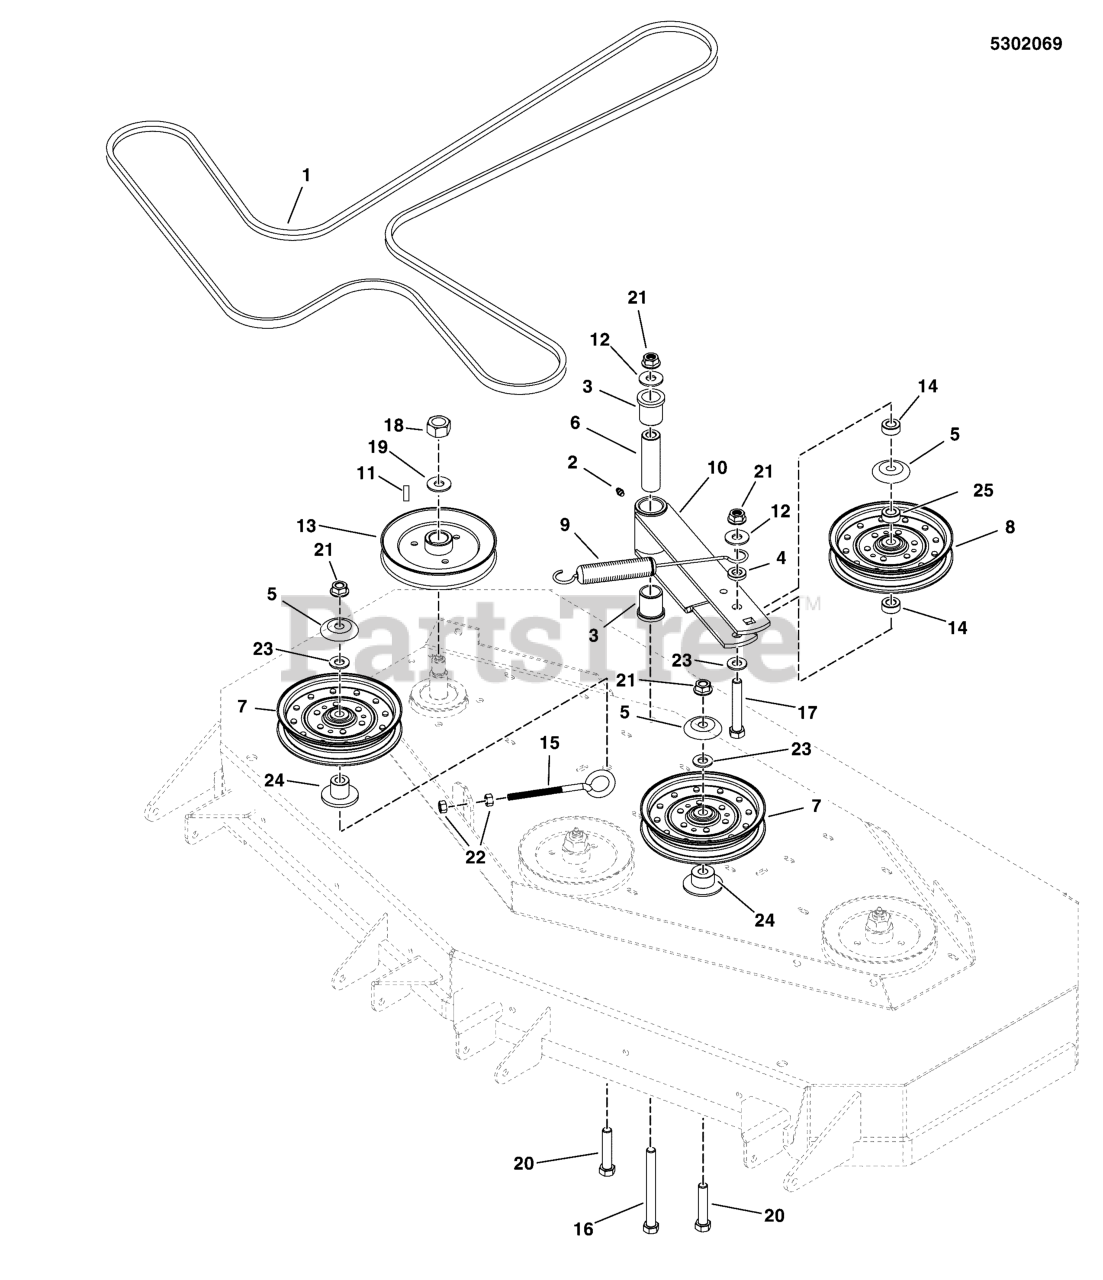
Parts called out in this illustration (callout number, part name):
1	BELT, B-SEC, 184.9 EL, ARMID, WRAPPED
2	GREASE FITTING, 45 DEGREE
3	BUSHING, FLANGE
4	SPACER, .52 X 1.00 X .22, PM, CZ
5	SHIELD, PULLEY BEARING
6	SPACER, .52 X 1.00 X 3.50
8	PULLEY, IDLER - 5
9	SPRING-EXTENSION, SWIVEL END
10	WELD, IDLER ARM - BLK
11	KEY, 1/4 SQ X 1-1/4
12	WASHER, 1/2 USS
13	PULLEY, SPIN, 6.5 OD X 25MM,
14	SPACER, .52 X 1.00 X .44
15	EYE BOLT, 3/8-16 X 6, 3.0 THREAD
16	BOLT-1/2-13 X 5 GD5 YZ
17	BOLT, 1/2-13 X 3-1/4, HEX HD, GD5, CZ (SV)
18	NUT, 3/4-16 HEX
19	WASHER, 3/4 BELLEVILLE
20	BOLT, 1/2-13 X 2-1/2" GD5 CZ
21	NUT, Hex Flange, Nylock, 1/2-13
22	NUT, 3/8-16 HEX, YZ
23	WASHER, 1/2 SAE
24	IDLER MOUNT
25	INSERT, BEARING
